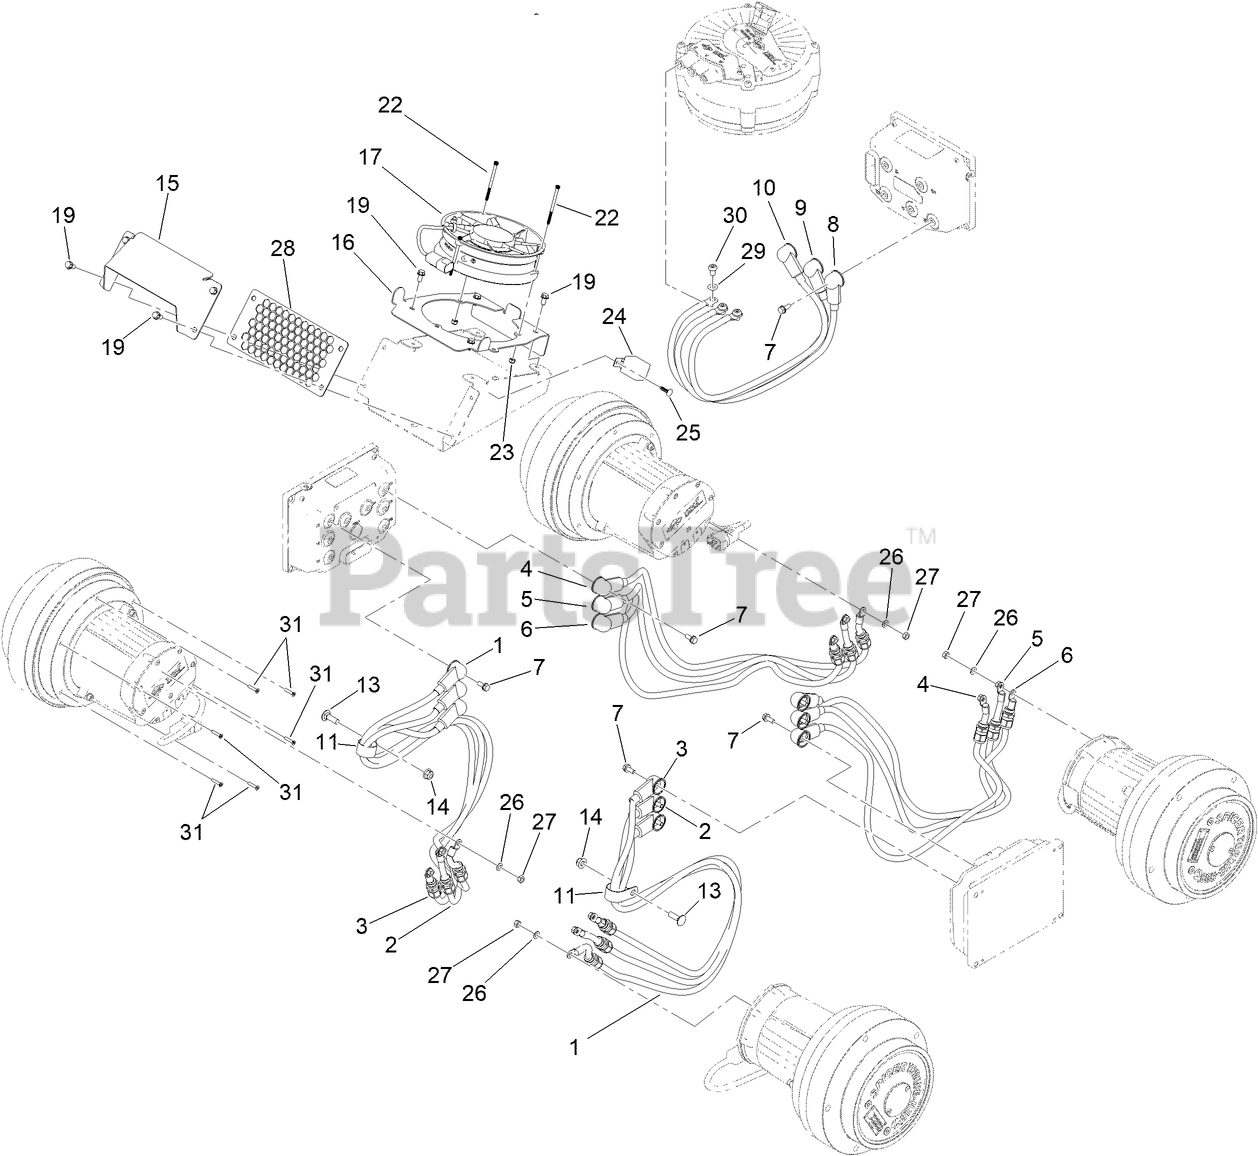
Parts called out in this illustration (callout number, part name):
1	CABLE-BATTERY, RD ASM
2	CABLE-BATTERY, RD ASM
3	CABLE-BATTERY, RD ASM
4	CABLE-BATTERY, RD ASM
5	CABLE-BATTERY, RD ASM
6	CABLE-BATTERY, RD ASM
7	SCREW-SEMS
8	CABLE-BATTERY, RD ASM
9	CABLE-BATTERY, RD ASM
10	CABLE-BATTERY, RD ASM
11	R-CLAMP
13	BOLT-CARR
14	NUT-HF, NI
15	DEFLECTOR-FAN
16	PLATE-ADAPTER,FAN
17	FAN-48V, 6.8"
19	SCREW-HWH
22	SCREW-HSH
23	NUT-LOCK
25	PLUG-PLASTIC
26	WASHER-SPRING
27	NUT-HEX
28	SCREEN - FAN GUARD
29	WASHER-BELLEVILLE
30	SCREW-HSBH
31	SCREW-TFH
